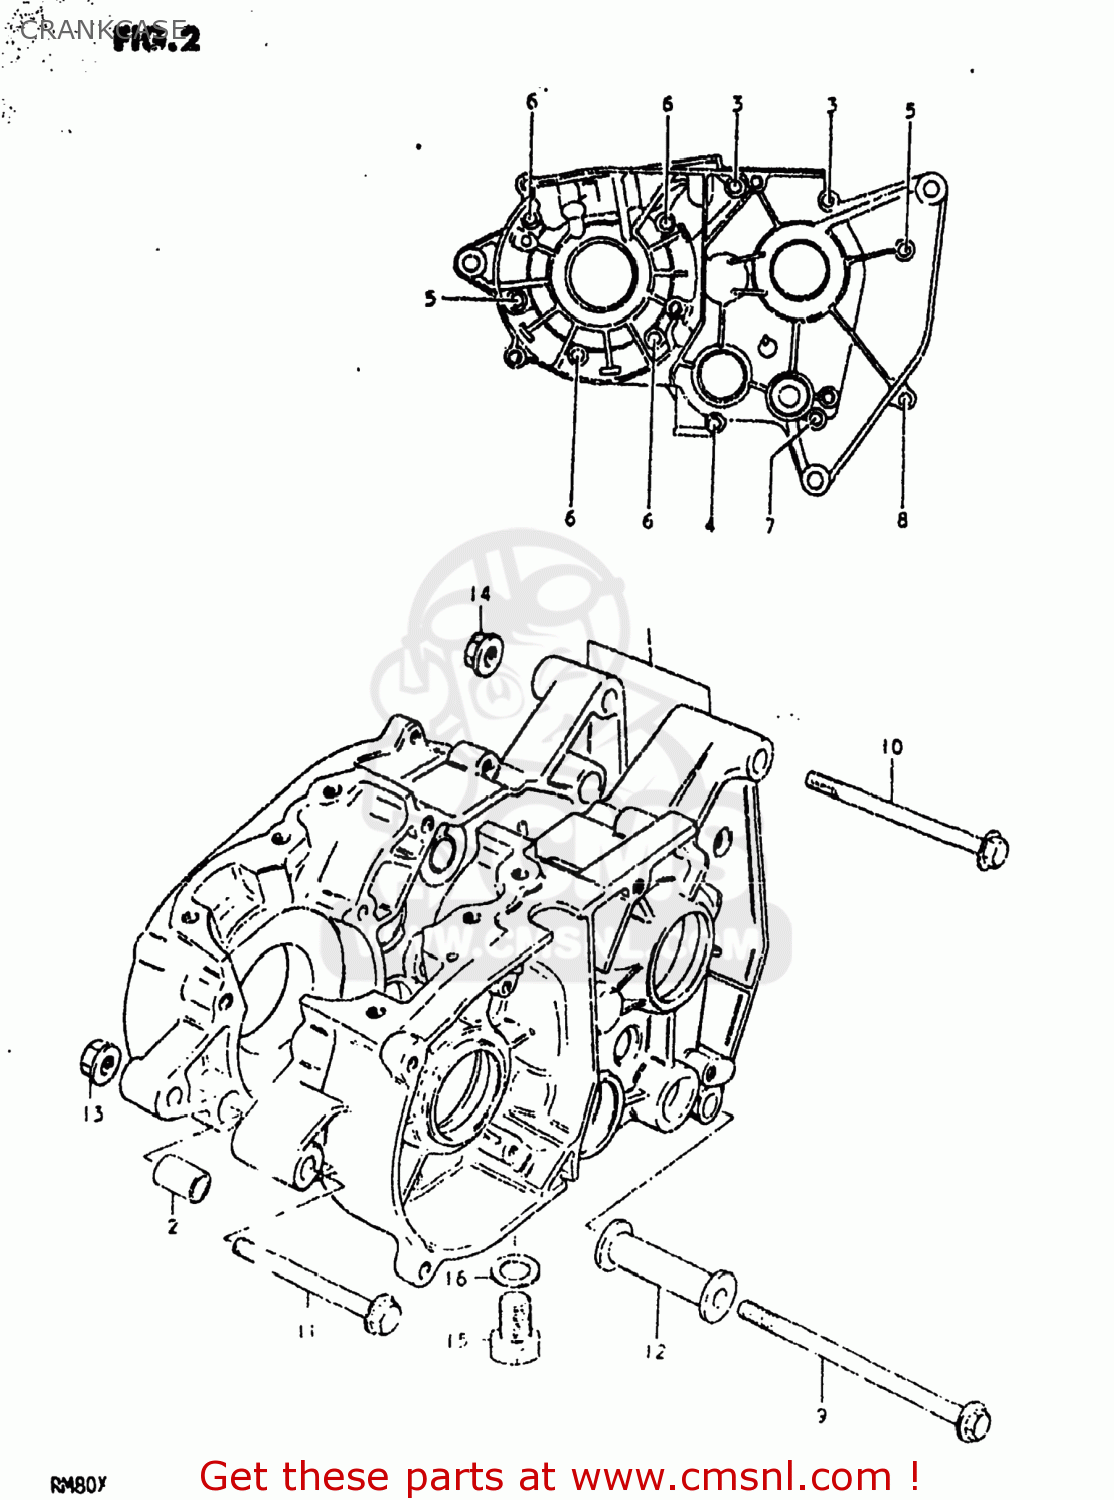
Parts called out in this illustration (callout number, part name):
1	CRANKCASE SET
2	PIN
3	CROSS SCREW (6 X 75)
4	SCREW
5	SCREW
6	SCREW (6X45)
7	SCREW (6X35)
8	SCREW
9	BOLT 10X20
10	BOLT
11	BOLT 8X75
12	SPACER,ENGINE MOUNTING
13	NUT
14	NUT
15	BOLT 10X20
16	GASKET(10X14X3.6) (NAS)
